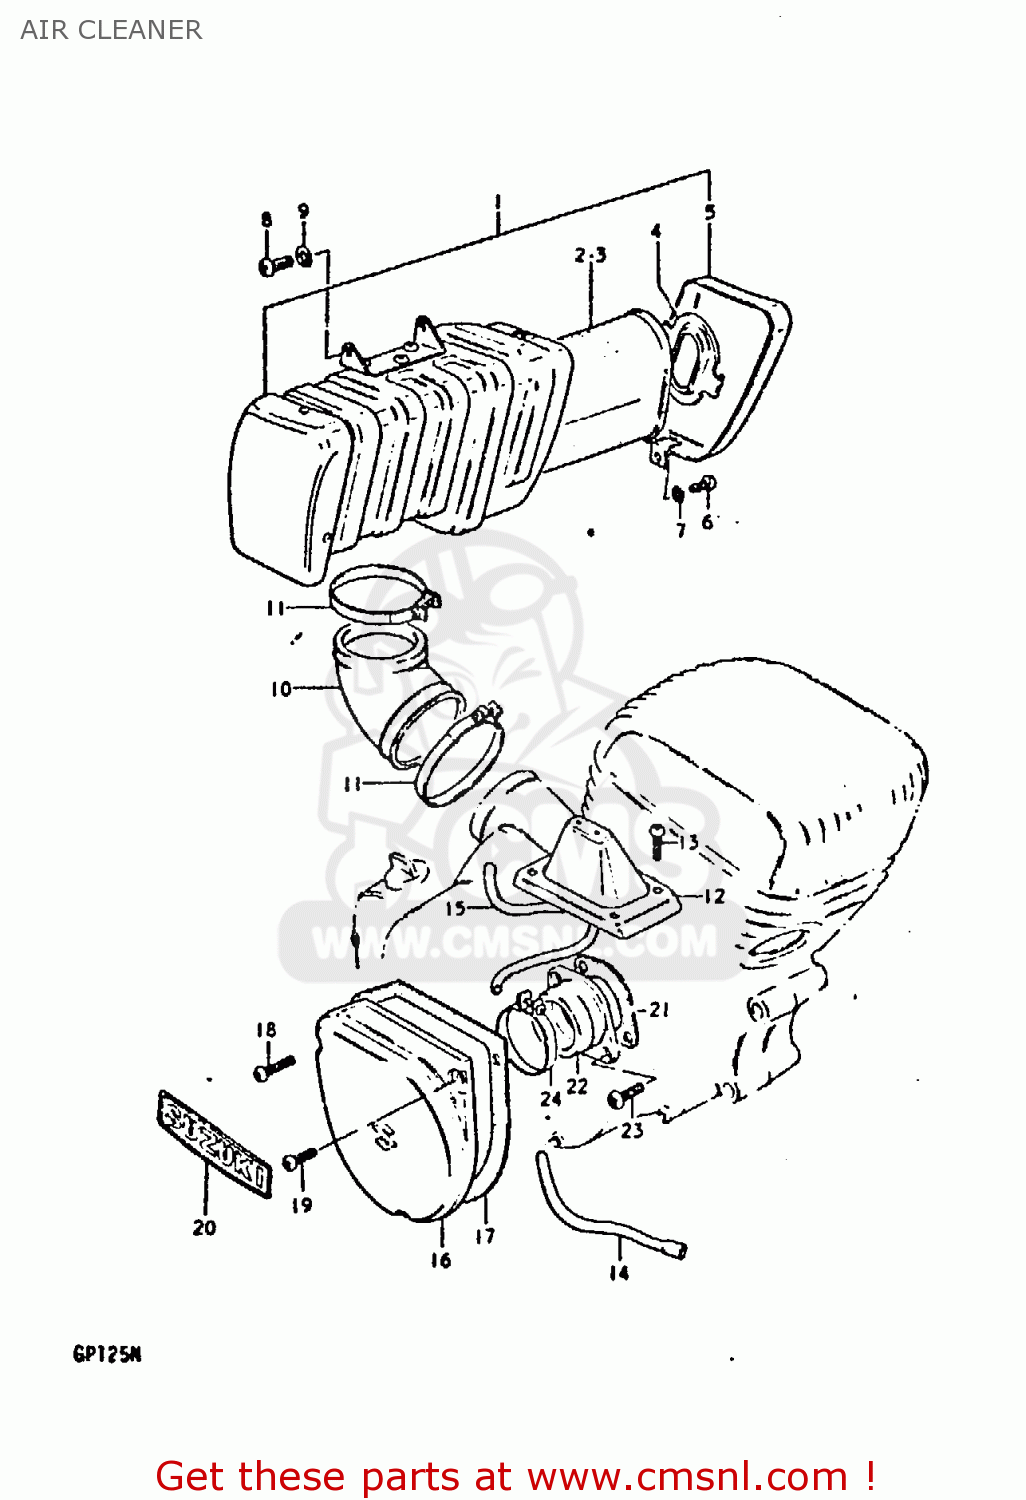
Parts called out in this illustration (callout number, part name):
8	SCREW 6X12
9	WASHER
10	HOSE,CARBURETOR AIR INLET
11	CLAMP
12	CAP,CARBURETOR TOP
13	SCREW
14	HOSE, AIR VENT (3.5*6.5*150)
15	HOSE
16	CAP, CARBURETOR INSPECTION
17	GASKET, CAP (MCA)
18	SCREW 5X20
19	SCREW
21	GASKET,CARBURETOR (NAS)
22	PIPE,INTAKE
23	SCREW
24	CLAMP
